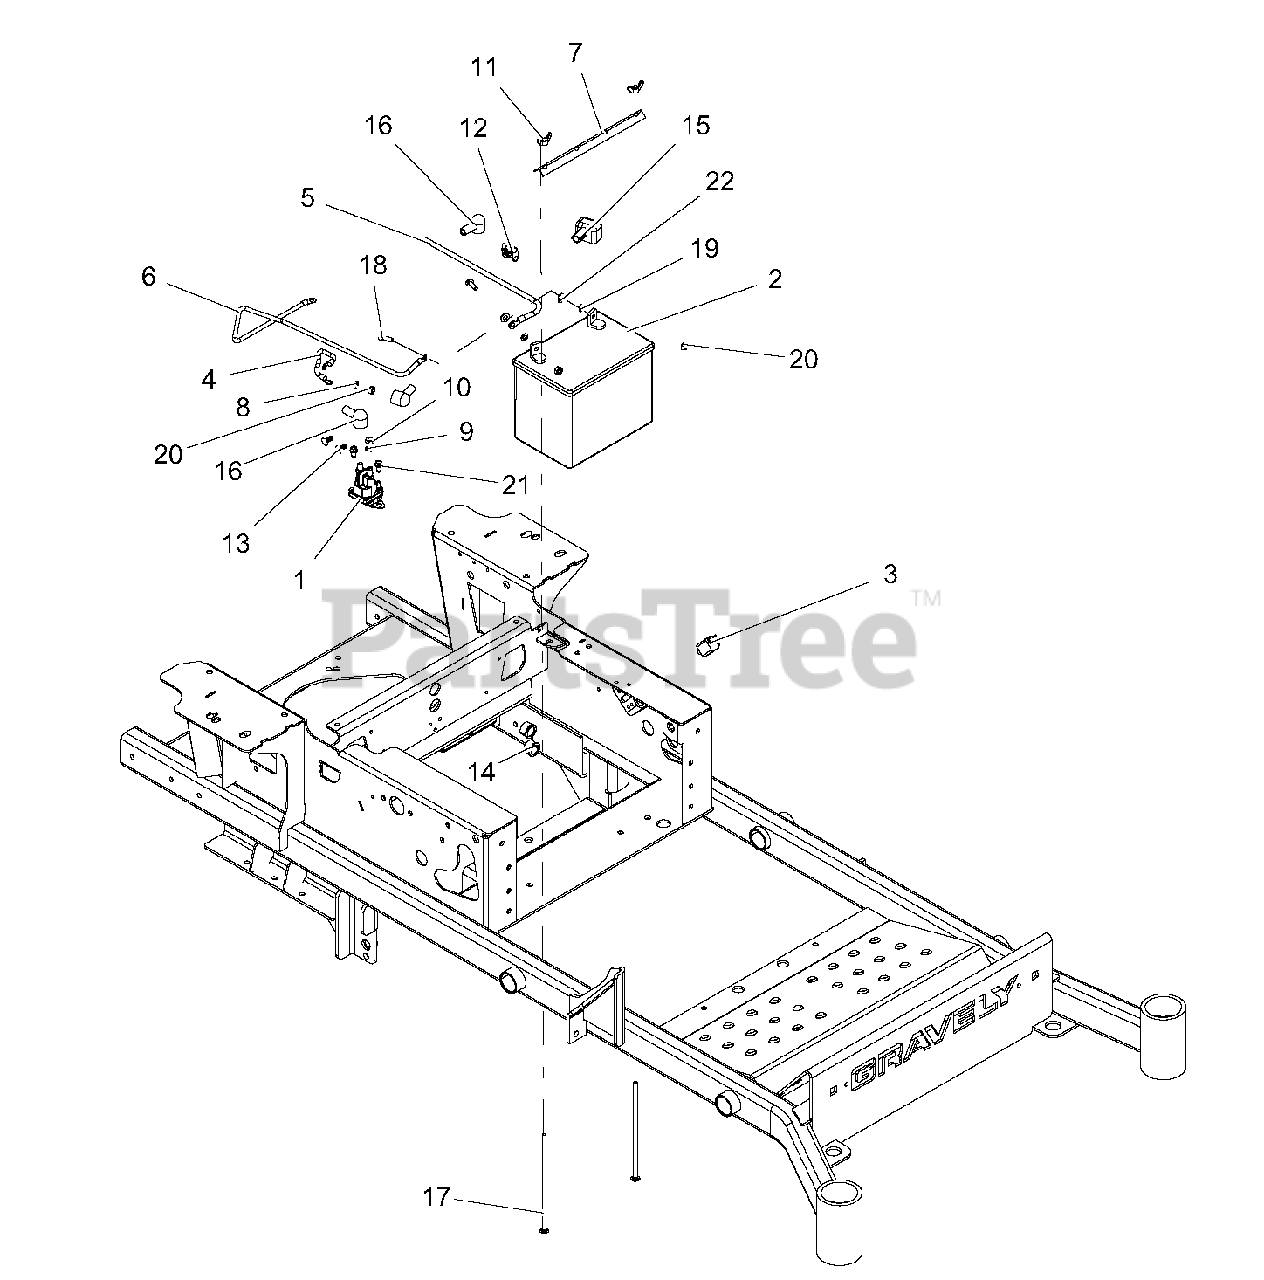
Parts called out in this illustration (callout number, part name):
1	SOLENOID, HP RTV
2	BATTERY,
3	SWITCH, SINGLE POLE N.O. (DELTA #6400-20)
4	CABLE, POSITIVE BATTERY 9.00"
5	CABLE, NEGATIVE BATTERY 24"
6	CABLE, STARTER .31 X 23.00 X .31
7	HOLD DOWN - BLK
8	@, WSHR-LK-EXT.262X.502X.026 YWZC
9	WSHR-LK-EXT .326X.599X.031 YWZC REV
10	NUT-JAM
11	NUT-LOCKING WING 1/4-20
12	CLIP, T, .31-.38
13	RIVET, .25 NYLON PANEL
14	BUSH, PANEL SNAP .687X.875X.56
15	INSULATOR
16	BOOT, EYELET TERMINAL
17	@BLT-RDHDSQNK .25-20X7.50 G2 YWZC
18	BLT-HEX .25-20X.75 GR5 YWZC
19	@WSHR-LK .25X.062 REG YWZC
20	NUT-HEX .25-20 YWZC
21	SCR-TAP .25-20X.50 HWH TR YWZ
22	@WSHR-FL-STL.281X.62X.065 YWZC
